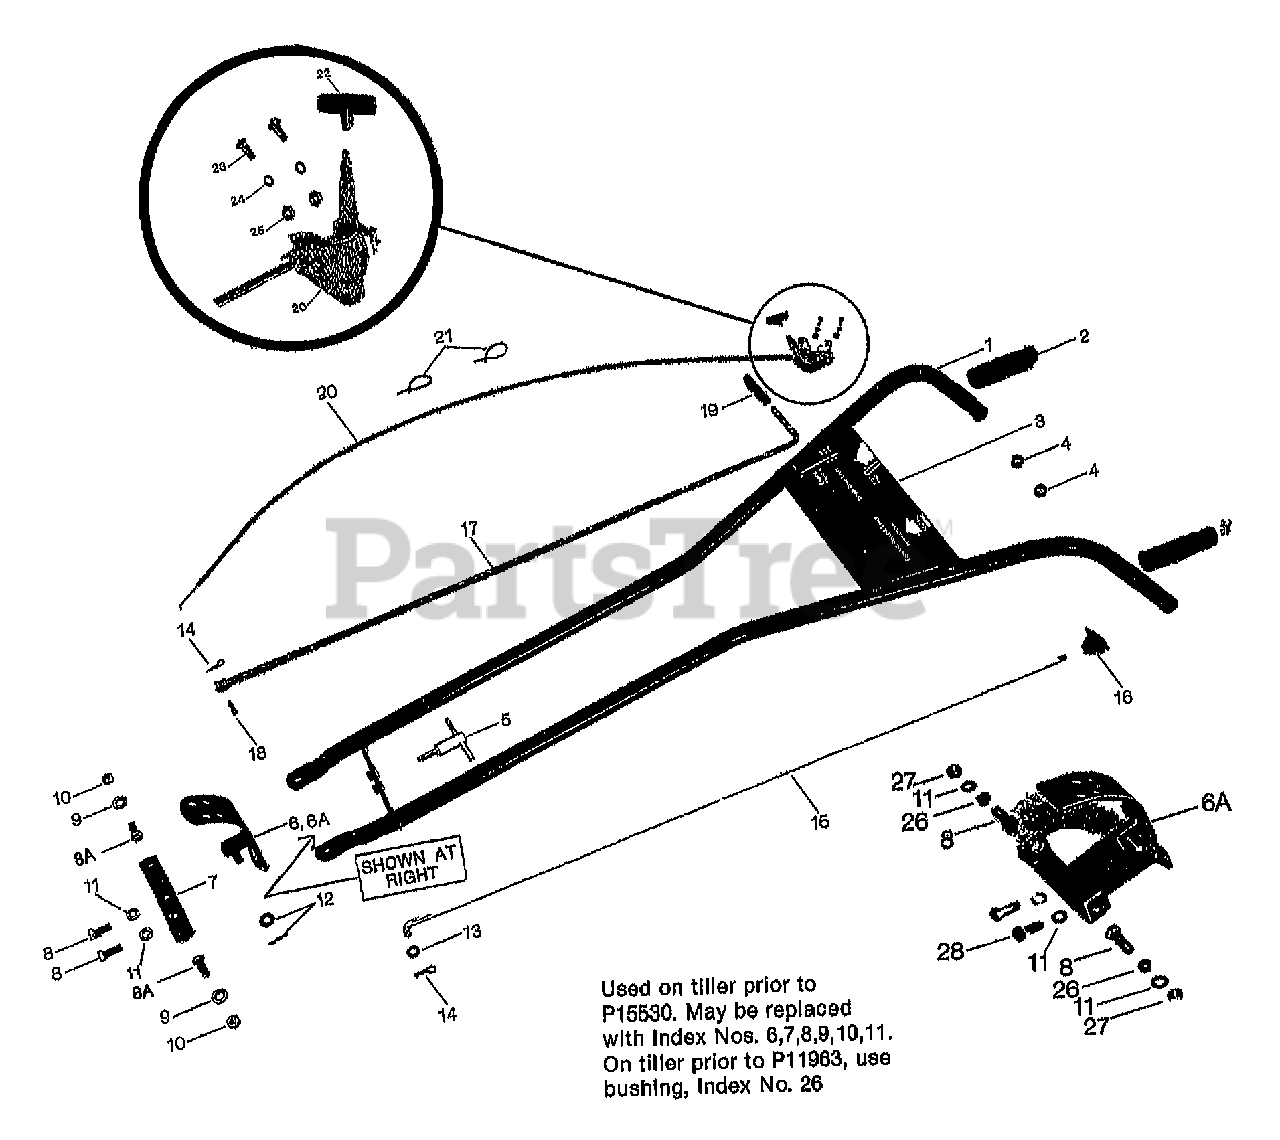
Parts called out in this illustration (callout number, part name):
1	ASSM-HANDLEBAR
2	GRIP-HANDLEBAR
3	DECAL-CONTROL PANEL
4	GROMMET-PLASTIC
5	ASSM-CLAMP
6	BRKT-HANDLEBAR MTG WELD
6A	BRKT-HANDLEBAR MTG WELD
7	BRKT-HANDLEBAR MTG
8	SCR-HH 3/8-16X1.0 G5 ZP
8A	SCR-HH 3/8-16X1.0 G5 ZP
9	WASHER-FLAT 3/8 SAE
10	NUT-H/LK 3/8-16
11	WASHER-LK .375 @ DEPL
12	WASHER & COTTER PIN - FOR IDLER ASSM. CLUTCH LEVER
13	WASHER-FLAT 5/16 SAE
14	PIN-CLIP .08
15	ASSM-DRIVE CONTROL ROD
16	KNOB-DRIVE CNTRL ROD
17	ROD-CONTROL
18	PIN-CLEVIS .183X1.0 ZP
19	GRIP-CONTROL ROD
20	CABLE-THROTTLE (COMPLETE)
21	TIE-RED
22	KNOB-THROTTLE CABLE
23	SCR-RH M10-32X.5 MACH
24	WASHER-LK M10
25	NUT-HH M10-32X.125
26	BUSHING-.5X.375X.3 (REPLACES 1113)
27	NUT-HEX 3/8-16 ZP
28	SCR-HH 3/8-16X1.25
